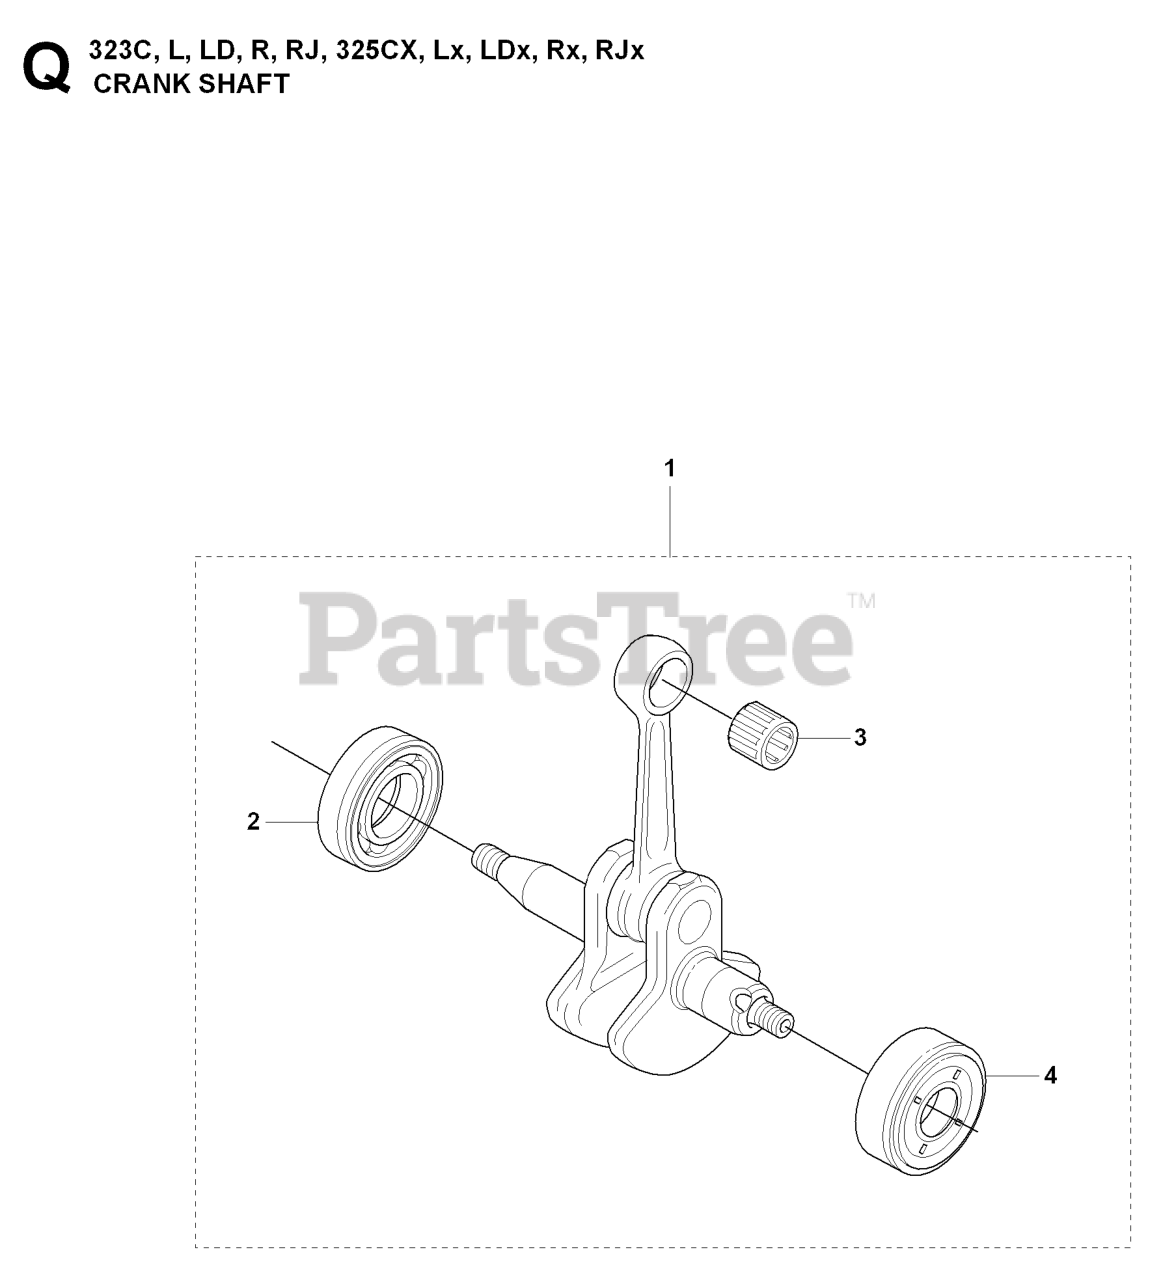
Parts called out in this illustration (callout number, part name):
1	ROD & BEARINGS COMPLETE
2	BEARING CAP
4	BEARING CAP
